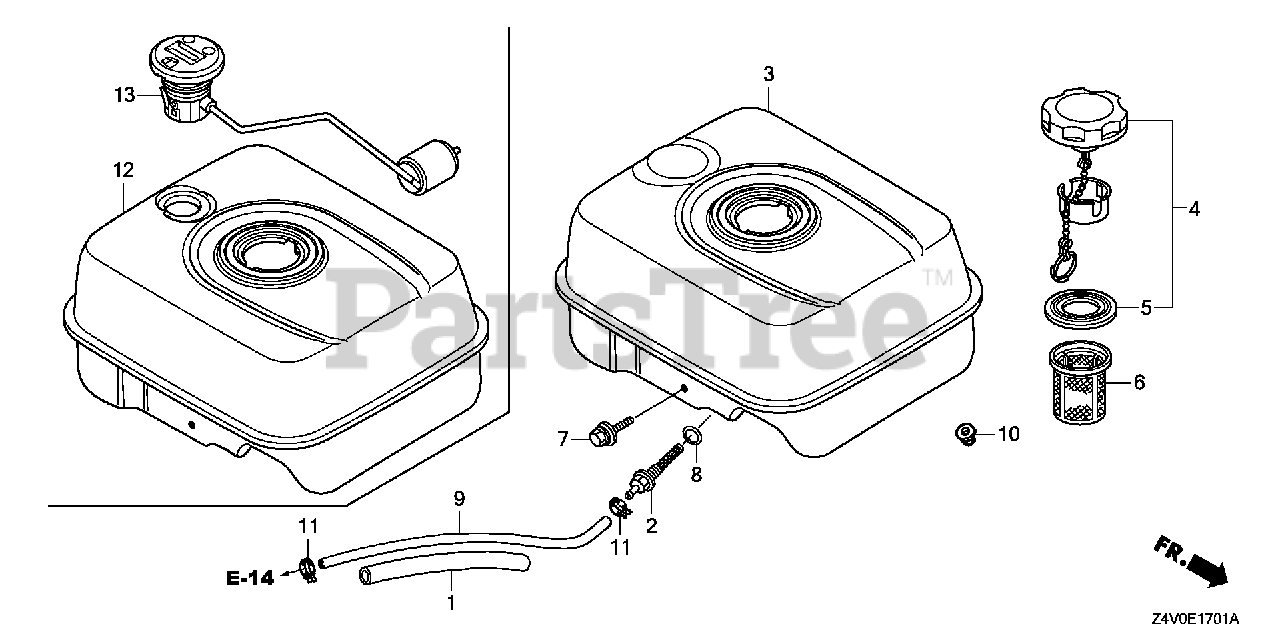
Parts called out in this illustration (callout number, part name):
1	RUBBER, SUPPORTER (107MM)
2	JOINT, FUEL TANK
3	TANK, FUEL *NH31* (MCKINLEY WHITE)
4	CAP, FUEL FILLER
5	GASKET, FUEL FILLER CAP
7	BOLT, FLANGE (6X34)
8	O-RING (14MM) (ARAI) Use up to Engine SN 2949254.
8	O-RING (14MM) (NOK)
9	TUBE, FUEL (4.5X145) (FKM)
10	NUT, FLANGE (6MM)
11	CLIP, TUBE (D8)
